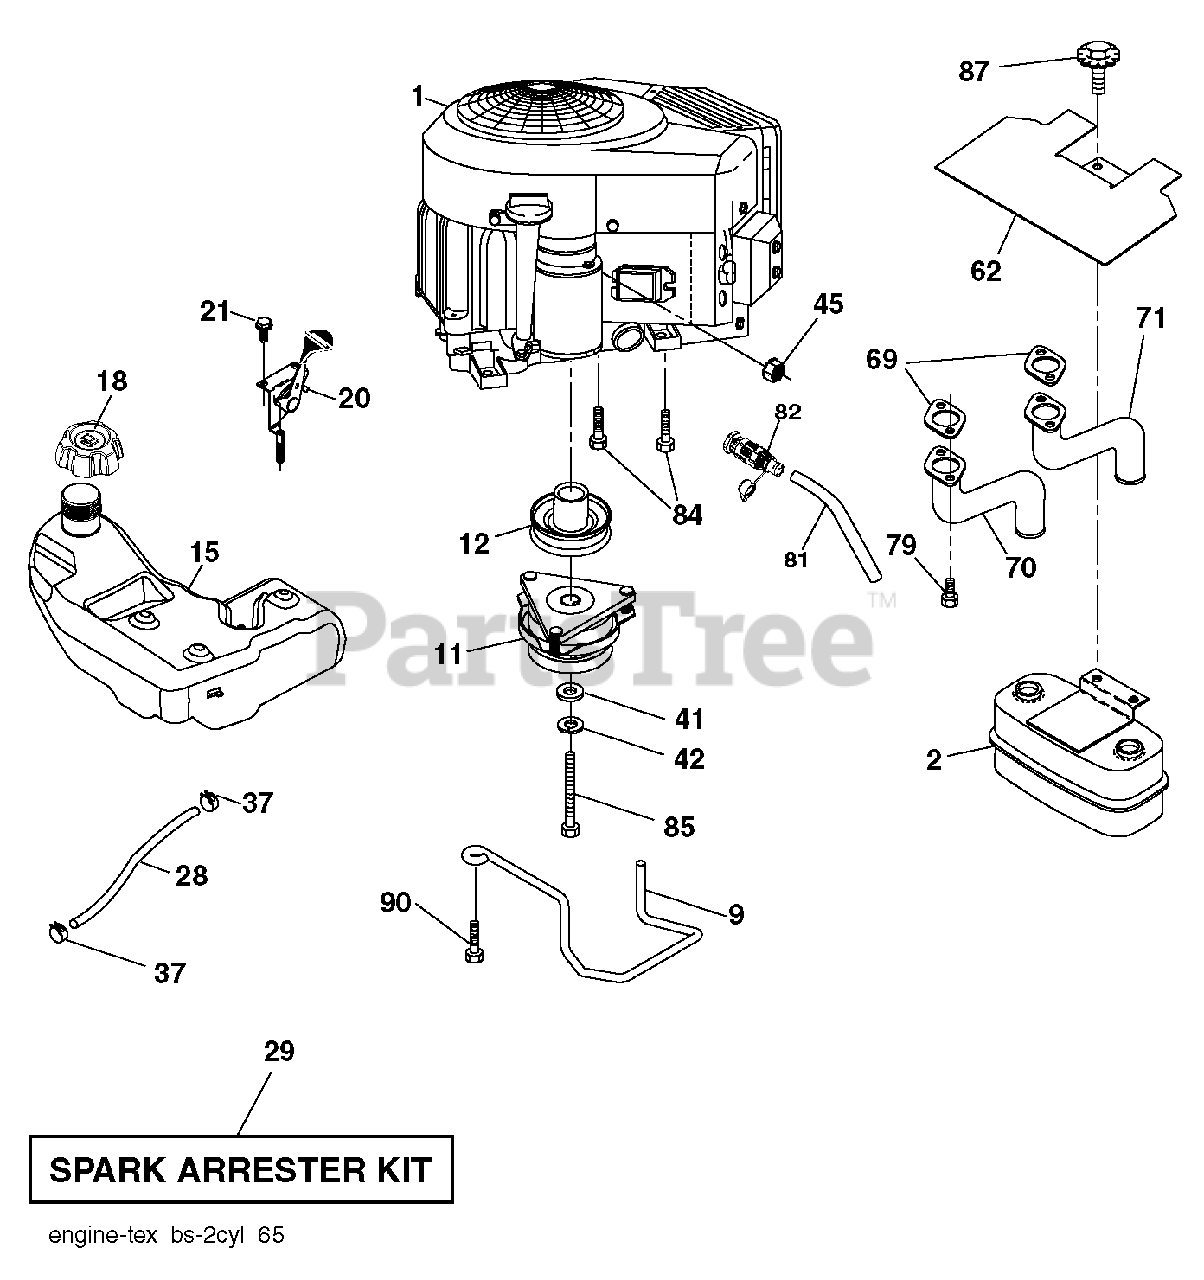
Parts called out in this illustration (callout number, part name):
2	MUFFLER.TWIN.CYL.LOW.TONE
9	KEEPER.BELT.ENGINE.4.2
11	CLUTCH
12	PULLEY.ENGINE.TUFFTORQ
15	TANK.FUEL.4GAL
18	CAP.ASM.FUEL.TANK.3"BLACK
20	CONTROL.TH/CK.COBRA.B&S.TWN.
21	SCREW.#10 X 0.750.BOS THREAD
29	ARRESTER SPARK (OPTIONAL)
37	HOSE CLAMP
42	LOCKWASHER
45	NUT
62	SHIELD.HEAT.MUFFLER
69	GASKET.MUFFLER
70	TUBE MANIFOLD LH
71	EXHAUST TUBE RH
79	SCREW.SOCKET.HEAD.5/16-18
81	TUBE, DRAIN OIL ASM.
82	VALUE.OIL.DRAIN
84	SCREW.3/8-16
85	BOLT HEX 7/16-20X4-1/4"
87	BOLT, 5/16-18 X 1 3/4
90	SCREW 3/8-16X1
